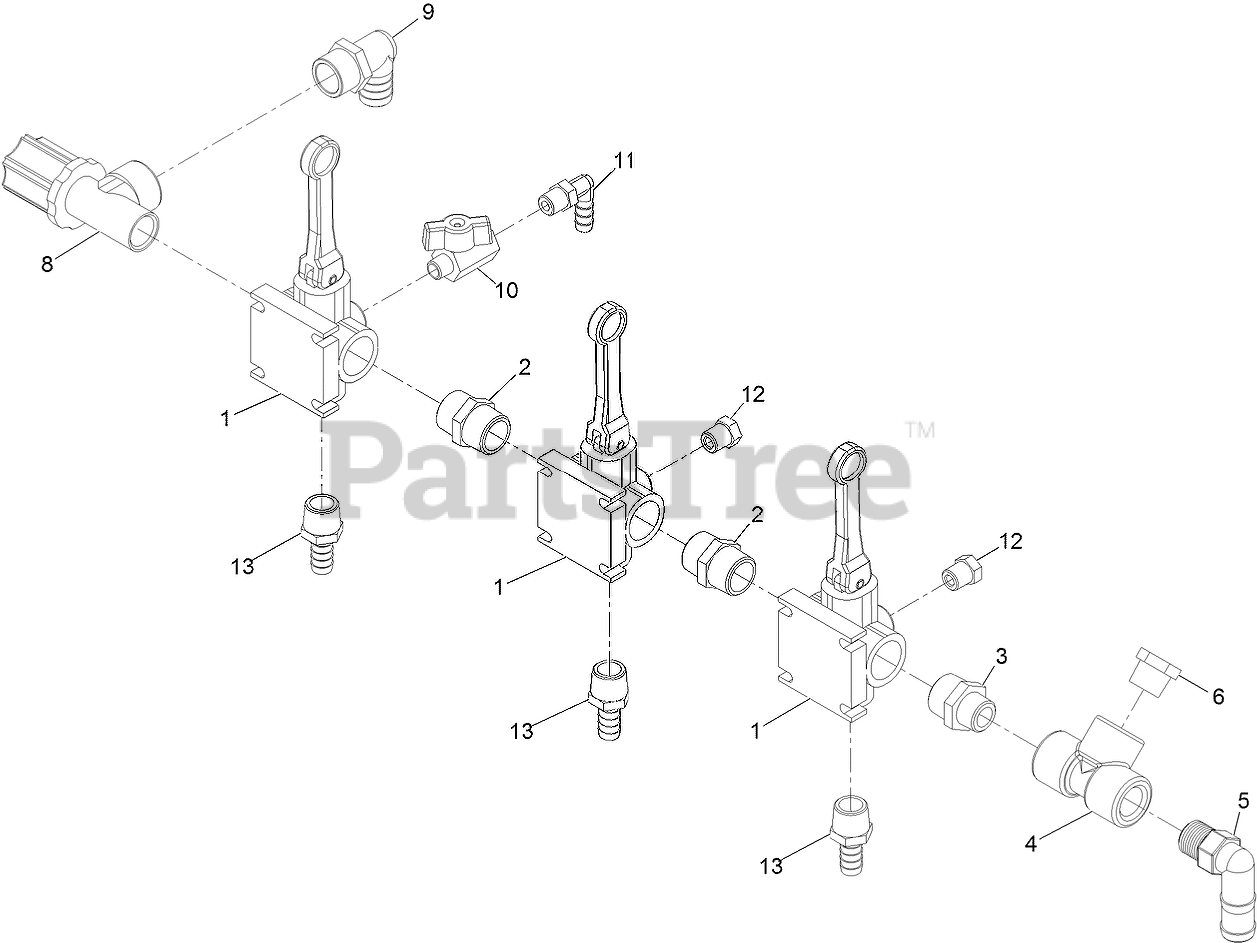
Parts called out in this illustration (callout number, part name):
1	VALVE-DIRECTO
2	FITTING-NIPPLE
3	FITTING-NIPPLE
5	ELBOW-90
6	FITTING-REDUCER
8	VALVE-THROTTLE
9	FITTING-ELBOW, 90
10	VALVE-CHROME, 1/4
11	FITTING-ELBOW, 90
12	PLUG-VALVE
13	FITTING-HOSEBARB
